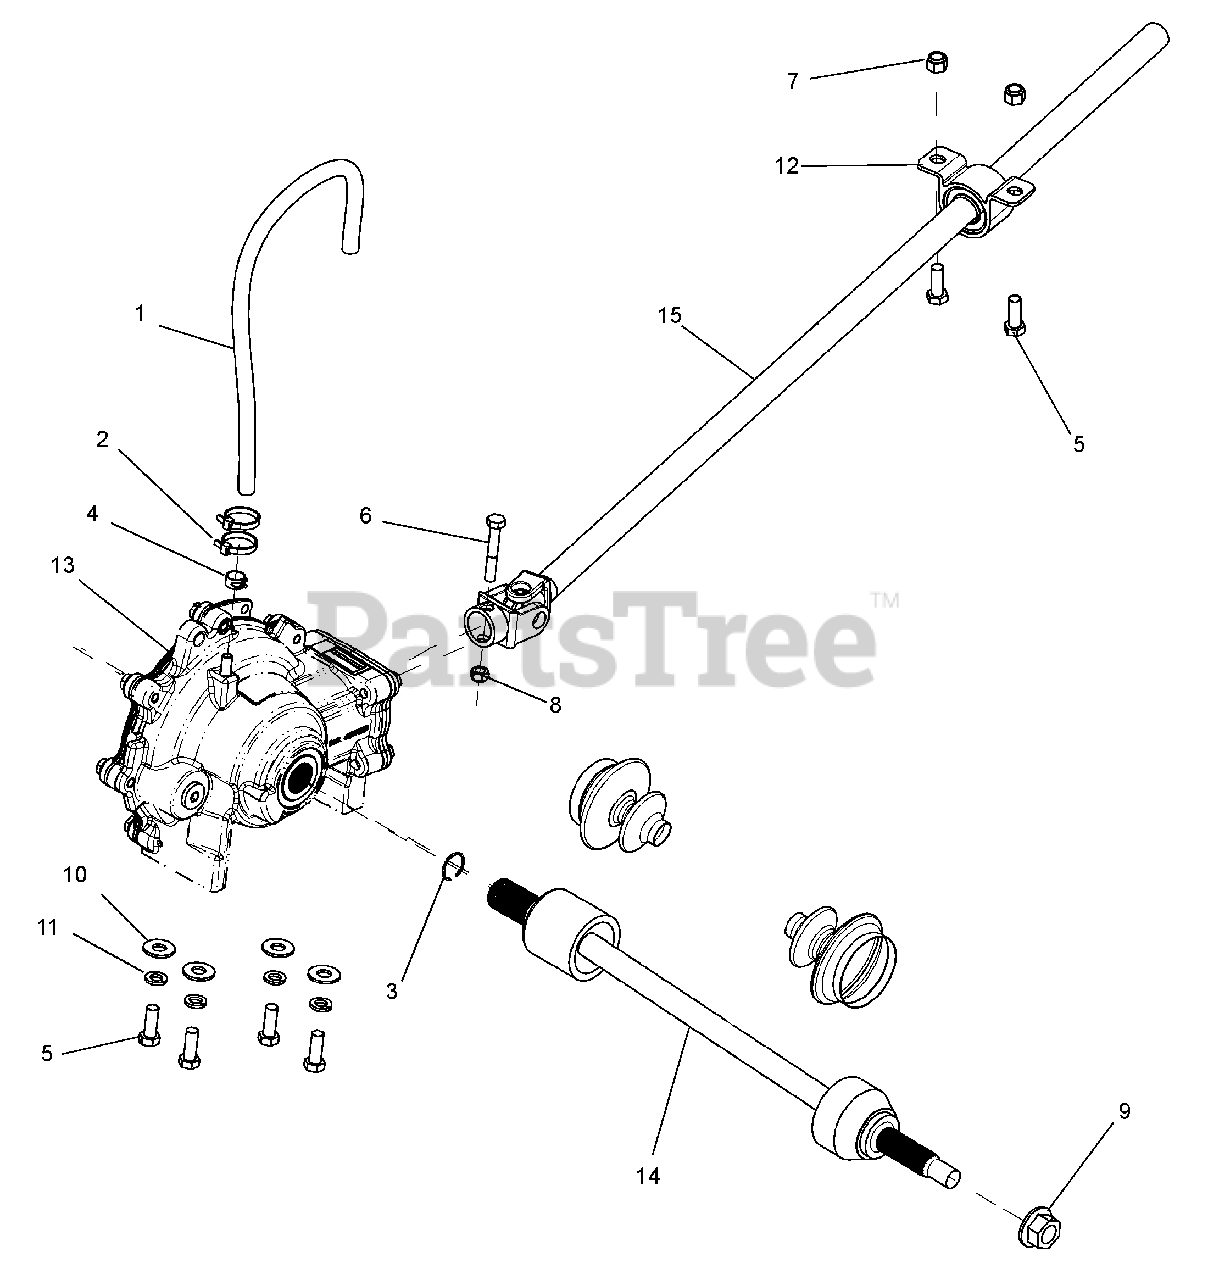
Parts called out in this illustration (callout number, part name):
1	VENT HOSE 17.5LG 4 X 4 GBOX
2	CABLE TIE 2 DIA MIN – BLK
3	SPRING CIR CLIP .95OD X .063 WIRE
4	CLAMP, FUEL LINE
5	HHCS .38-16 X 1 GR5 YWZC
6	BOLT, HEX .31-18 X 2 GR5 YWZC
7	NUT, NYLOCK .38-16 YWZC
8	NUT, NYLOCK .312-18 YWZC
9	NUT, HEX M16 X 1.5 TOP LOCK PLT
10	WASHER FLAT .438 X 1.00 X .083 YWZC
11	WASHER LOCK .38 X .094 REG YWZC
12	PILLOW BLOCK BEARING TRUCK
13	FRONT DIFFERENTIAL WITH ELECTRIC CLUTCH
14	FRONT AXLE SHAFT STANDARD
15	DRIVELINE 4 X 4 NT/ST
